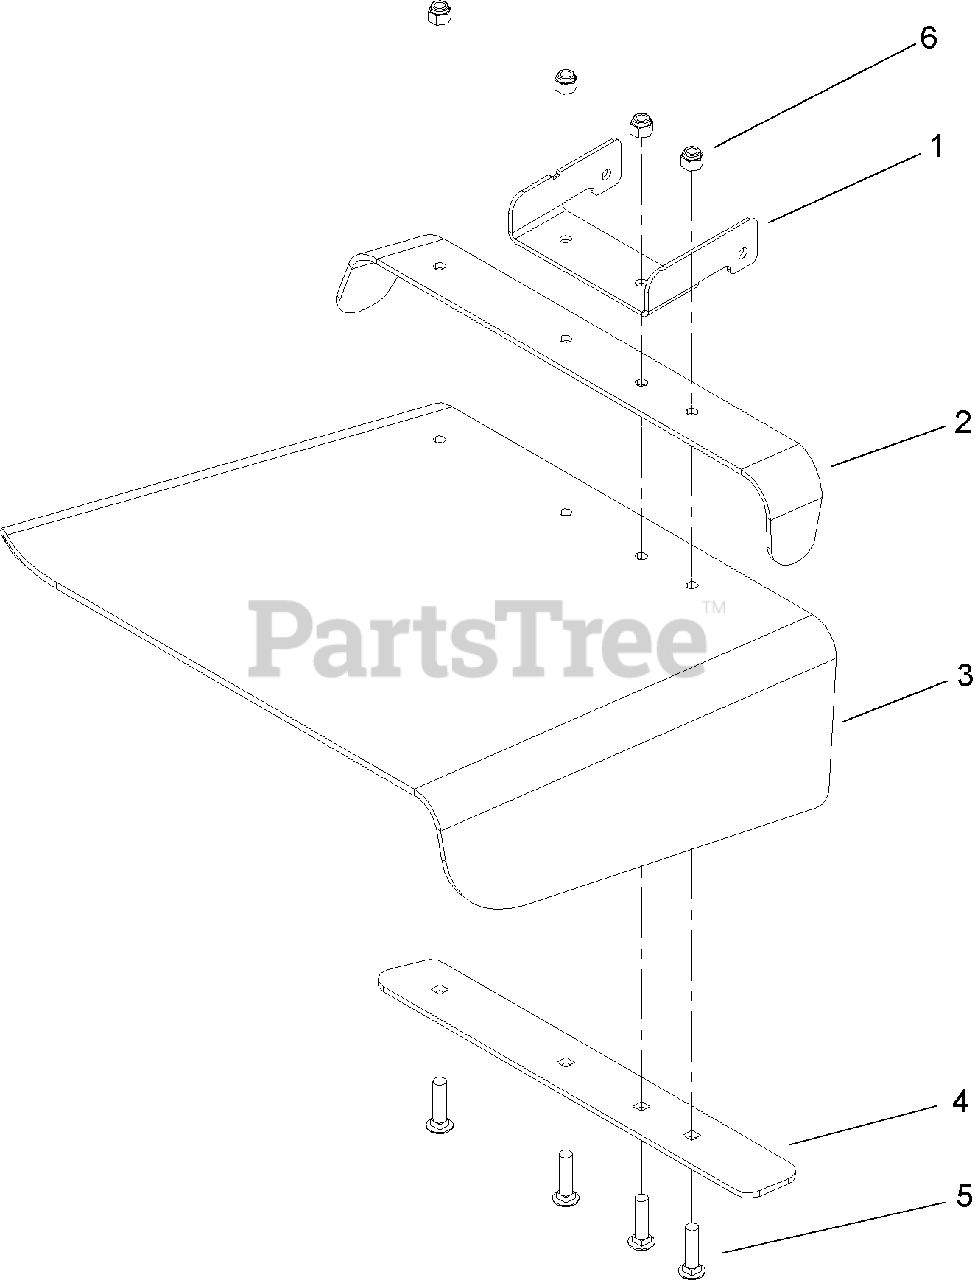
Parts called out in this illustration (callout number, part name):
1	HINGE-DEFLECTOR
2	SUPPORT-DISCHARGE
3	DEFLECTOR-RUBBER
4	STRAP-DISCHARGE
5	SCREW-CARR
6	NUT-LOCK, NI
